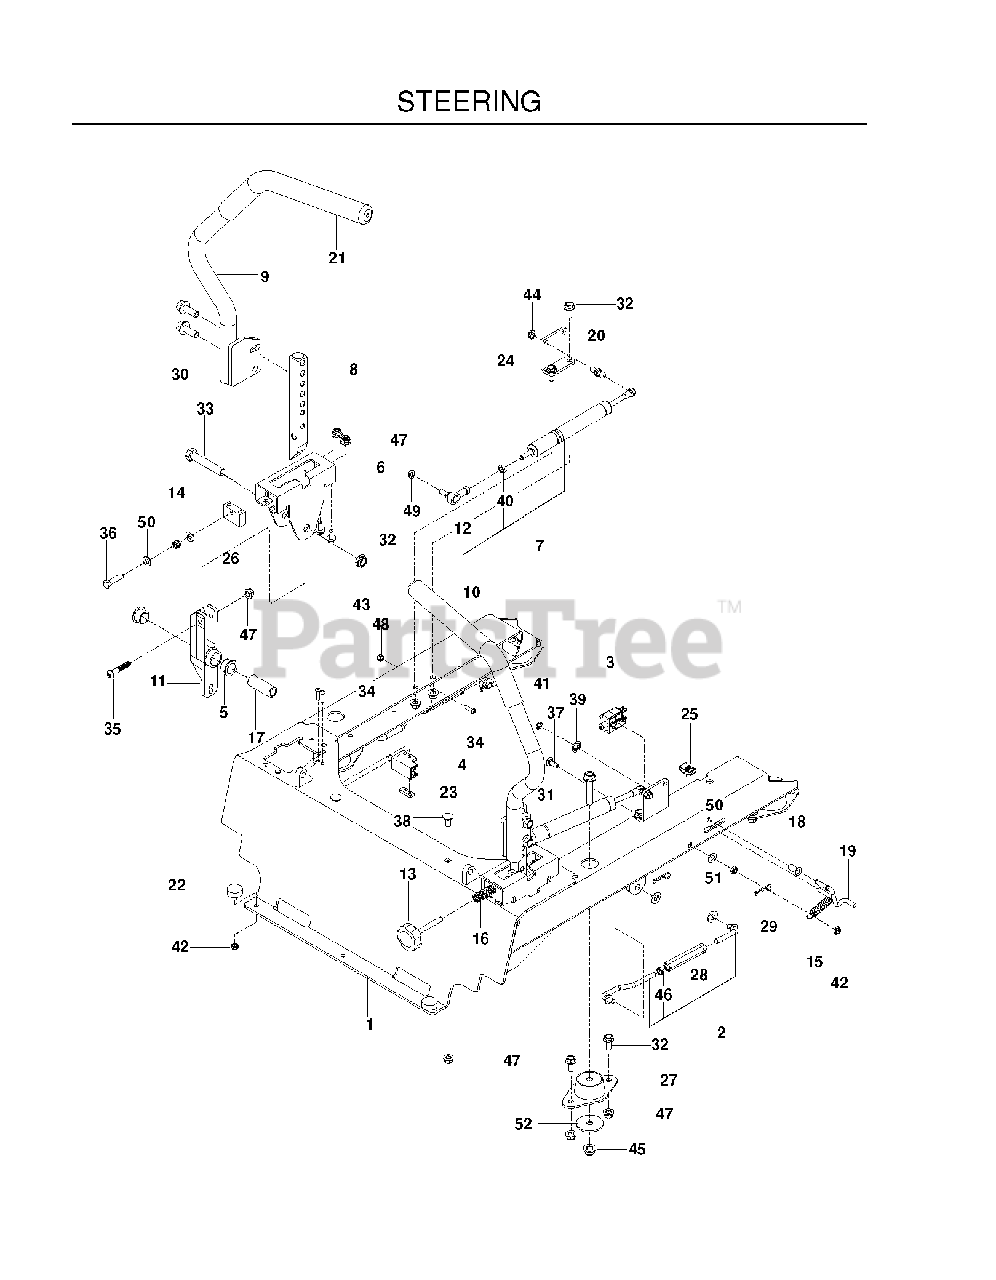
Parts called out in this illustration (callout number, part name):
1	FRAME SEAT MOUNT ORANGE
2	ASSEMBLY, SEAT STRUT
3	SWITCH, BRAKE 3P
4	SWITCH INTERLOCKT
5	BEARING, FLANGE
6	BRACKET, CONTROL
7	ASSEMBLY, DAMPENER
8	LEVER, MOTION
9	LEVER.WITH GRIP.RT
10	LEVER.WITH GRIP.LT
11	LEVER.CONTROL.SHORT
13	KNOB
15	SPRING, EXTENSION
16	SPRING COMPRESSION 2.0
17	SPACER, PIVOT CONTROL
18	BUSHING, 1/4 FLANGE
19	LINK, SWITCH
20	STUD.BALL.10MM
21	GRIP - DRIVE LEVER 12"
22	NUT
23	TAPPED PLATE
24	BRACKET.DAMPNER
25	U-CLIP 5/16-18 NUT RETAINER
26	BLOCK.TRACKING
27	MOUNT, ISO
28	TURNBUCKLE, 3/8
29	HAIRPIN #2
30	HHFS 3/8-16 X 1 GRD 5 ZD
31	HHFS 3/8-16 X 2.0 GD 5
32	HHFS 5/16-18 X 3/4
33	HCS 1/2C X 2 3/4
34	SCR #10-24 X .75 SKT HD BLK
35	SCREW 5/16-18 X 1 3/4 BTN-HD
36	HCS 5/16C X 1 1/4
37	RHSNB 1/4C X 3/4
38	BOLT 5/16C X 3/4" CARRIAGE
39	NUT 3/8 PALNUT RTNG BLK PHOS
40	NUT M8 X 1.25 STD HEX
41	NUT PUSH
42	JAM NUT 1/4C (2 2 PW01)
43	NUT 1/2-13 HEX JM NYL
44	NUT 5/16 NYLOC
45	NUT 3/8-16 HEX FLG NYLOC ZD
46	NUT 3/8-24 JAM
47	5/16-18 NYLOC FLANGE NUT
48	NUT 10-24 NYLOC
49	WASHER 5/16 LOCK
50	FLAT WASHER 5/16 SAE
51	WASHER 3/8 SAE FLAT
52	WASHER, 3/8 SPEC
